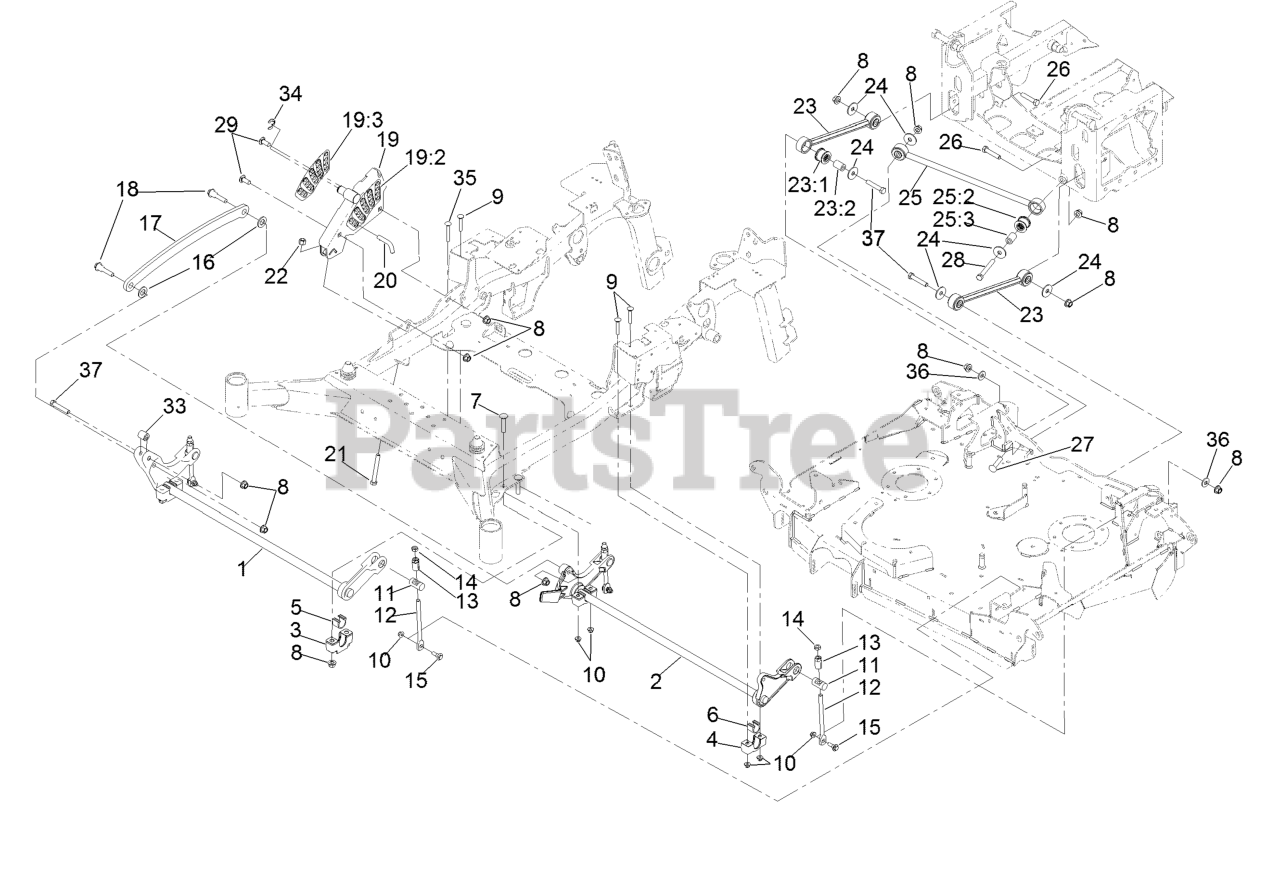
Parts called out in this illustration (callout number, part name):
1	Decklift-Front
2	Lift-Deck, Rear
3	Support-Cross Shaft, Bearing
4	Support-Cross Shaft, Bearing Rear
5	Bearing-Cross Shaft, Front
6	Bearing-Cross Shaft, Rear
7	Bolt-Carriage 1/2-13 X 2 1/2 Spl Neck
8	Nut-Lock 1/2-13
9	Bolt-Carriage 3/8-16 X 2 1/4
10	Nut-Nyloc 3/8-16 Flg
11	Trunnion
12	Link-Adjuster, Deck Lift
13	Adjuster-Lift, Deck
14	Nut-Jam 1/2-13
15	Screw-Hex Flange 3/8-16 X .80
16	Washer-3/4 SAE
17	Link-Lift, Deck
18	Screw-Hex Flange 1/2-13 X 1.90
19	HOC ASM
19:2	Decal-Height Of Cut
19:3	Decal-Height Of Cut, Outer
20	Pin-HOC
21	Bolt-HH 1/2-13 X 4 Tap
22	Nut-Nyloc 1/2-13
23	Deck Strut ASM
23:1	Bushing-Suspension, Rubber
25	Panhard Rod ASM
25:2	Bushing-Suspension, Rubber
26	Screw-HH 1/2-13 X 2 1/2
27	Bolt-Carriage 1/2-13 X 2 1/2
28	Screw-HH 1/2-13 X 4
29	Screw-CARR, Short Neck
33	Spacer-Pivot
34	Ring-Retaining
35	Bolt-Carriage 3/8-16 X 2 3/4
36	Washer-Spring Disc 1/2
37	Screw-HH 1/2-13 X 2 3/4
